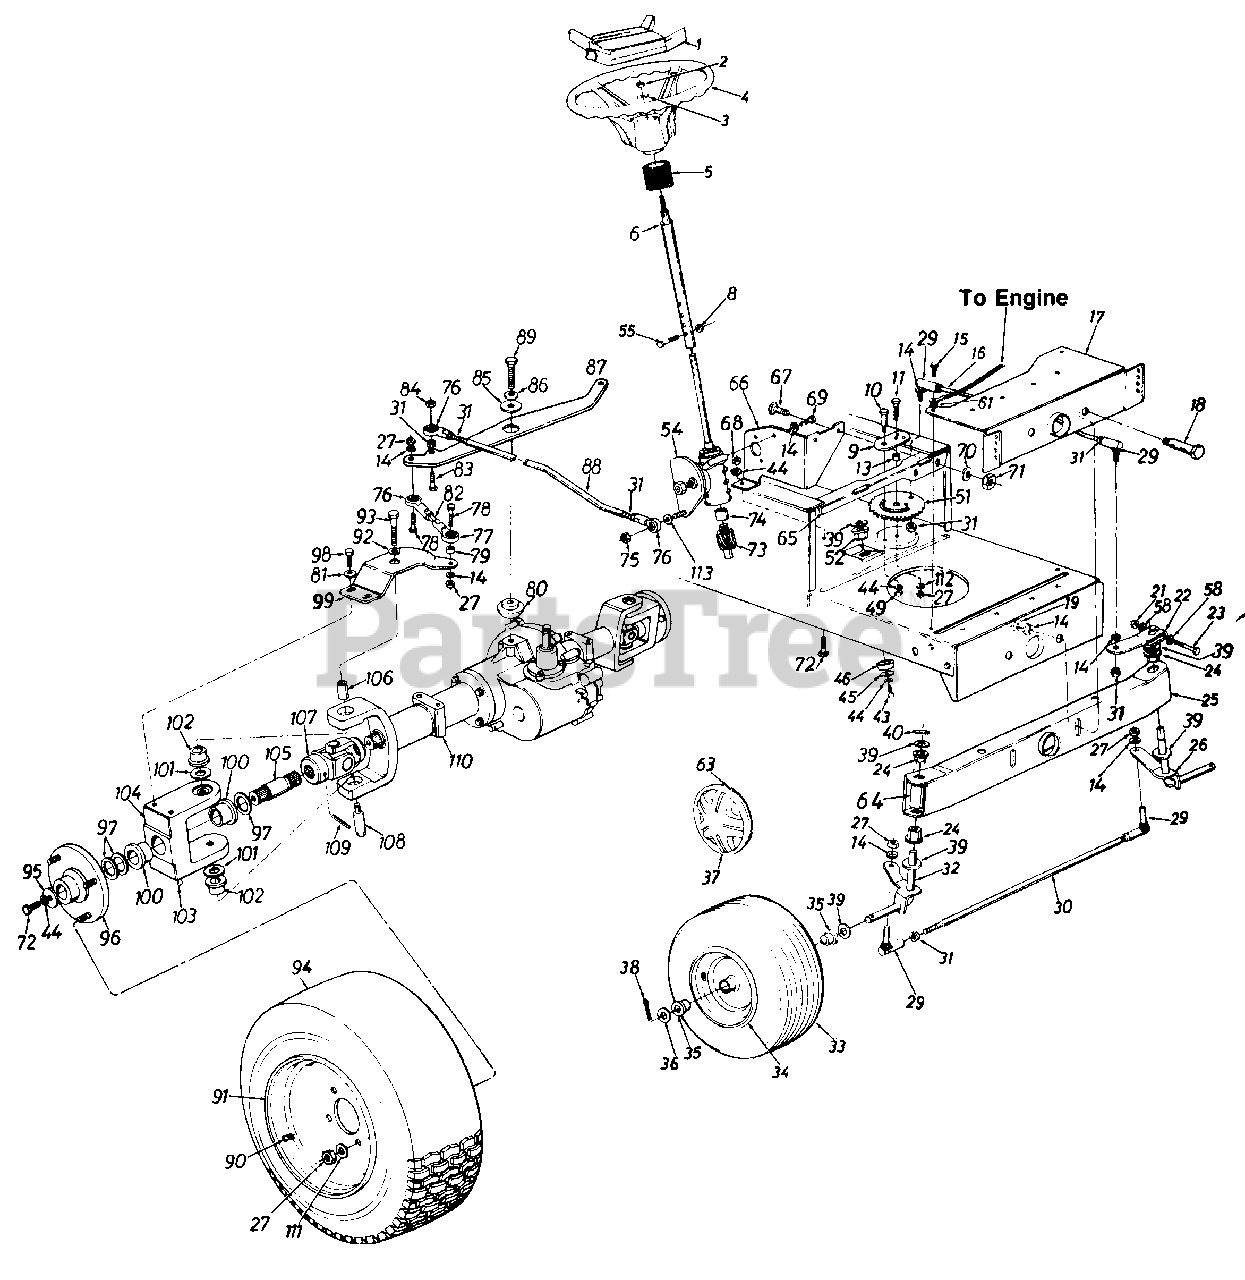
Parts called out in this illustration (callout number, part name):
1	Steering Wheel Insert
2	Hex L-Nut 5/16-24 Thd.
3	Belleville Wash. .345" I.D.
4	Steering Wheel
5	Steering Bellow
6	Steering Column Ass'y.
8	Hex L-Nut 1/4-20 Thd.
9	Retainer Plate
10	Shoulder Bolt .437" Dia. x .35" Lg. 5/16-18 Thd.
11	Hex Bolt 3/8-24 x 1.0" Lg. (Grade 5)
13	Spacer .380" I.D. x .625" O.D. x .227"
14	L-Wash. 3/8" I.D.
15	Hex Wash. Hd. Self-Tap Scr.
16	Steering Drag Link
17	Front Pivot Brkt.
18	Shoulder Bolt .498" Dia. x 2.04" Lg. 3/8-16 Thd.
19	Hex Nut 3/8-16 Thd.
21	Hex Cent. L-Nut 5/16-24 Thd.
22	Steering Arm Front Axle
23	Hex Bolt 5/16-24 x 2.00" Lg. (Grade 5)
24	Hex Flg. Brg. .634" I.D.
26	Front Axle Ass'y. L.H.
27	Hex Nut 3/8-24 Thd.
29	Ball Joint 3/8-24 Thd.
30	Tie Rod
31	Hex Jam Nut 3/8-24 Thd.
32	Front Axle Ass'y. R.H.
33	Wheel Ass'y. Comp.
34	Front Wheel Rim Only
35	Flange Bearing
36	Fl-Wash. .635" I.D. x 1.59" O.D.
37	Front Hub Cap
38	Cotter Pin 1/8" Dia. x 1.25" Lg.
39	Fl-Wash. .640" I.D. x .24" O.D.
40	Spring Roll Pin
43	Hex L-Bolt 5/16-18 x .62"
44	L-Wash. 5/16" I.D.
45	Fl-Wash. .33" I.D. x 1.25" O.D.
46	Spacer (Plastic)
49	Hex Nut 5/16-18 Thd.
51	Steering Gear Segment
52	Hex Flg. Brg. .634 I.D.
54	Steering Ass'y.
55	Hex Bolt 1/4-20 x 1.31" Lg.
58	Wave Wash. .32" I.D. x .62"
61	Ext. L-Wash. 5/16" I.D.
63	Spring Clip
64	Plastic Tube
65	Horizontal Cross Bracket
66	Vertical Mounting Bracket
67	Hex Bolt 1/4-28 x .75" Lg.
68	Hex Nut 5/16-24 Thd.
69	Hex Bolt 3/8-16 x 1.0" Lg.
70	Bell-Wash. .265" I.D. x .75"
71	Hex Nut 1/4-28 Thd.
72	Hex Bolt 5/16-24 x .75" Lg.
73	Pinion Shaft
74	Steering Shaft Splined Coupler
75	Hex L-Nut 3/8-24 Thd.
76	Rod End 3/8-24 Thd. R.H.
77	Rod End 3/8-24 Thd. L.H.
78	Hex Bolt 3/8-24 x 1.5" Lg. (Grade 5)
79	Spacer .38" I.D. x .625"
80	Shld. Spacer .51" I.D.
81	Bell-Wash. .38" I.D. x .88"
82	Tie Rod
83	Hex Bolt 3/8-24 x 1.25" Lg.
84	Hex Patch L-Nut 3/8-24 Thd.
85	Fl-Wash. .531" I.D. x 1.75"
86	Bell-Wash. .505" I.D. x 1.0"
89	Hex Bolt 1/2-13 x 1.5" Lg. (Grade 5)
90	Air Valve
93	Hex Bolt 1/2-20 x 2" Lg.
95	Fl-Wash. .33" I.D. x 1.25"
96	Wheel Flange Ass'y.
97	Fl-Wash. 1.0" x 1.56"
98	Hex Bolt 3/8-24 x .75" Lg.
101	Fl-Wash. .76" I.D. x 1.5"
102	Flange Brg. 3/4" I.D.
103	Grease Fitting
104	Wheel Brg. Housing
105	Outer Axle
106	Pivot Sleeve
107	U-Joint
108	Pivot Pin
109	Grooved Roll Pin l.0" Lg.
110	Axle Horn Ass'y.
111	Bell-Wash. .38" I.D. x .88"
112	Bell-Wash. .39" I.D. x 1.38"
113	Fl-Wash. .385" I.D. x .62"
